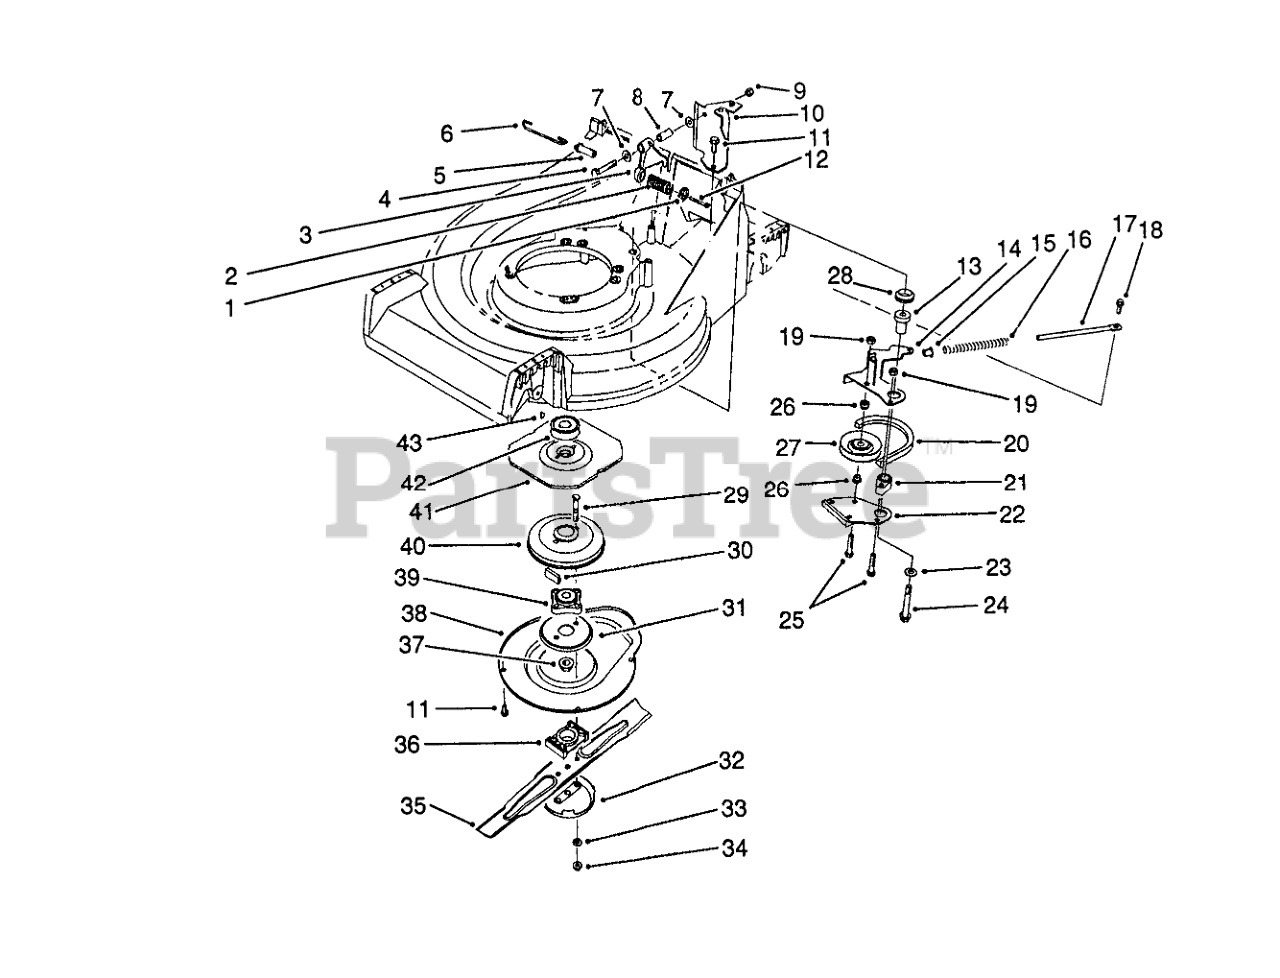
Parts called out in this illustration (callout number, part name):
1	RETAINER-SPRING
2	COMPRESSION SPRING
3	CRANK
4	SCREW-HH
5	SPRING PIN
6	CONTROL LINK
7	WASHER-PLAIN
8	STRAIGHT BUSHING
10	Bracket-Cable Support
11	SCREW-HWHTF
12	SCREW-HWHTF
13	BBC PM BUSHING
14	Lever
15	SPACER
16	COMPRESSION SPRING
17	SPRING ROD
18	SCREW-SHOULDER
19	NUT-LOCK, NI
20	V-BELT
21	BRAKE PLATE HUB
22	BRAKE SHOE
23	WASHER-PLAIN
24	3/8-16 X 2-3/4 CAPSCR
25	SCREW-HH
26	IDLER PULLEY HUB
27	PULLEY-IDLER
28	V-RING SEAL
29	BOLT-BLADE
30	DAMPENER-VIBRATION
31	Screen-BBC
32	Anti Scalp Cup
33	WASHER
34	NUT-LOCK
35	Key
36	SPACER-BLADE
37	NUT-LOCK, NI
38	Cover
39	HUB ASM
40	BRAKE DRUM
41	FLYWHEEL - BBC
42	PULLEY
43	KEY-WOODRUFF
